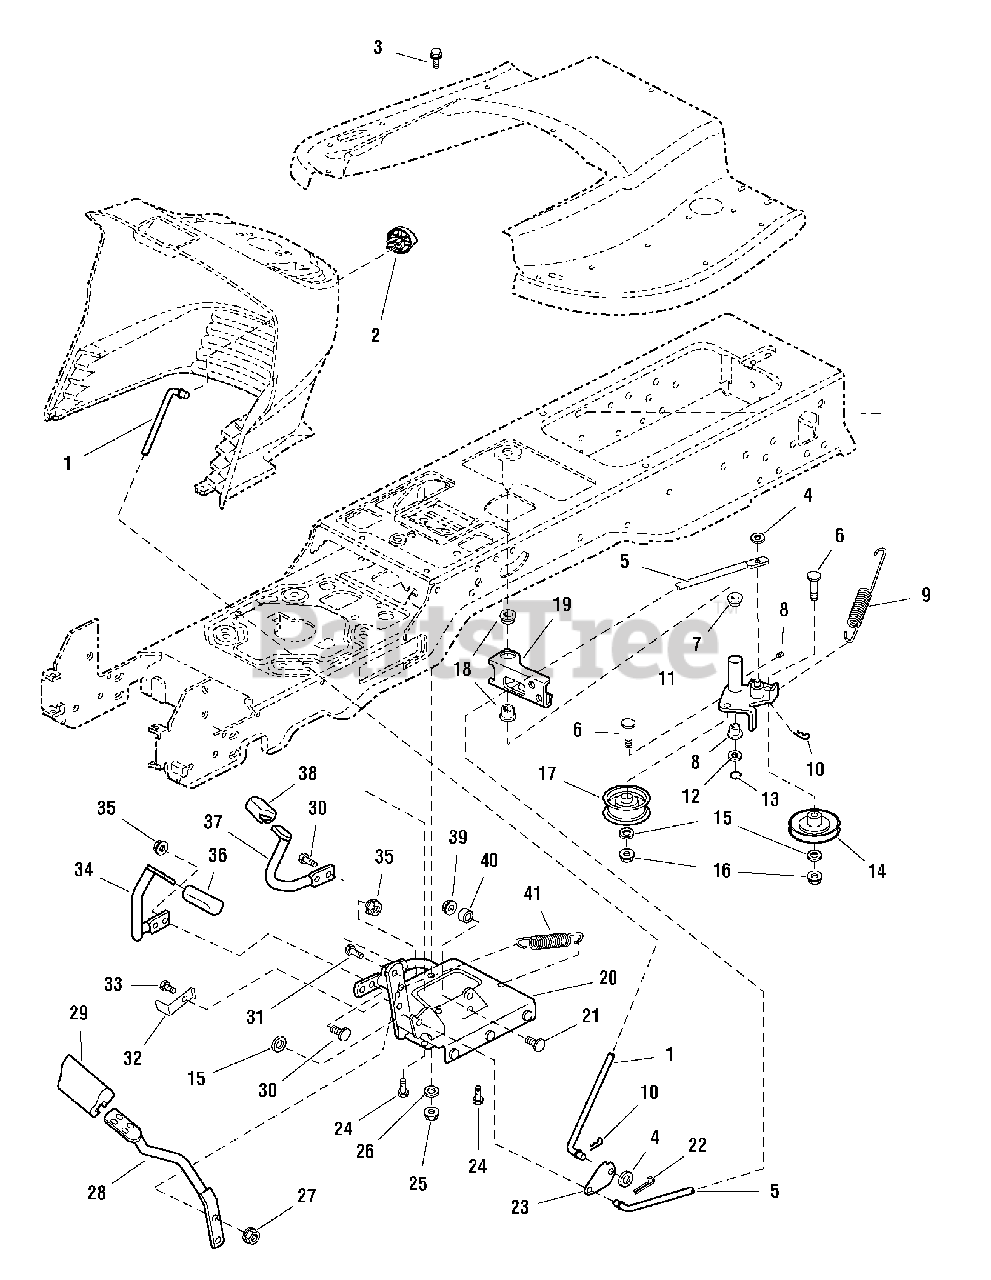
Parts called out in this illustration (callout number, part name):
1	ROD, Brake Lock
2	KNOB, Push On, Red Plastic "P"
3	CAPSCREW, Hex Flange Whiz Lock, 5/16-18 x 3/4
4	WASHER, 5/16, Black
5	ROD, Brake
6	CARRIAGE BOLT, 3/8-16 x 1 3/4
7	BUSHING, 5/8 x 3/4 x 3/4, Nylon
8	FITTING, Lube, 1/4
9	SPRING, Extension
10	PIN, Quick
11	ARM & HUB ASSEMBLY, Idler
12	WASHER, 5/8
13	RING, Clipring Extension
14	PULLEY, w/Bearing
15	WASHER, 3/8
16	NUT, Hex Lock ESNA Light, 3/8-16
17	PULLEY, Idler
18	BUSHING, 1 x 1-1/8 x 5/8, Nylon
19	ARM, Brake
20	PEDAL ASSEMBLY, Foot
21	CARRIAGE BOLT, 1/4-20 x 1-1/4
22	PIN, Cotter, Black
23	LATCH, Brake
24	CAPSCREW, Hex Washer Head Taptite, 5/16-18 x 3/4
25	NUT, Hex Lock ESNA Light, 5/16-18
26	WASHER, 5/16, Black
27	NUT, Hex Flange Whiz Lock Large, 5/16-18
28	PEDAL, Brake
29	PAD, Brake Pedal
30	CARRIAGE BOLT, 5/16-18 x 7/8
31	CAPSCREW, 5/16-18 x 1
32	ACTUATOR, Switch 2.53" Long
33	CAPSCREW, Hex Washer Head Taptite, 3/8-16 x 3/4
34	PEDAL, Forward
35	NUT, Hex KEPS, 5/16-18
36	PAD, Foot Pedal Forward
37	PEDAL, Reverse
38	PAD, Foot Pedal Reverse
39	NUT, Hex Lock ESNA Light, 1/4-20
40	CAM, Roller
41	SPRING, Extension
